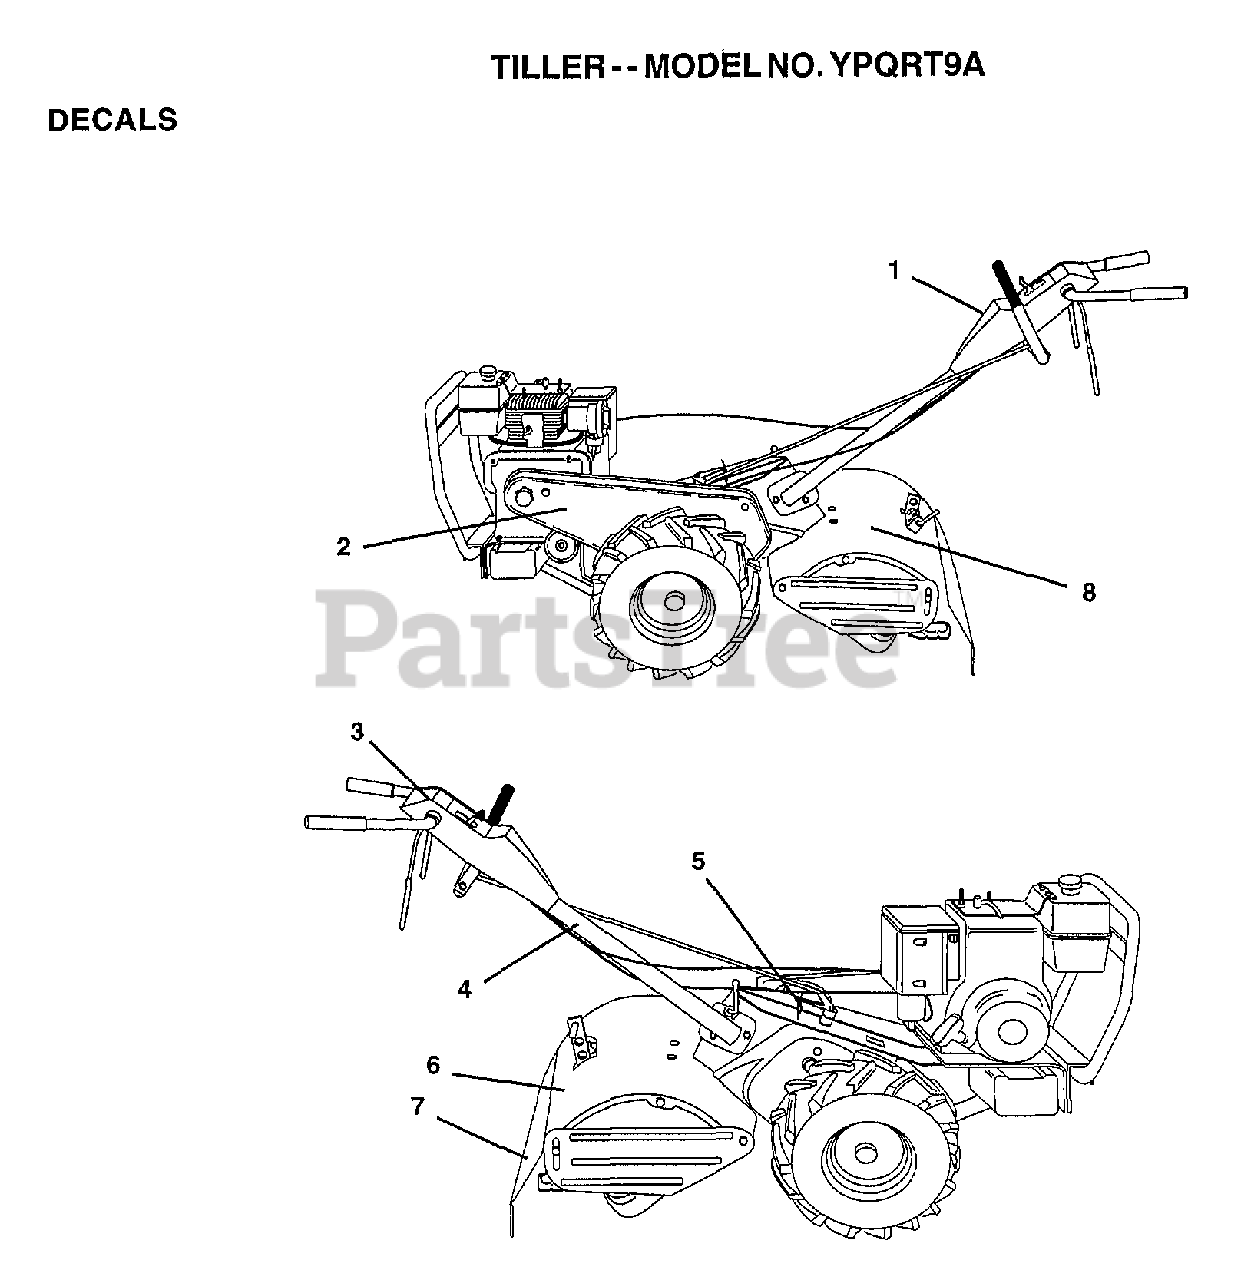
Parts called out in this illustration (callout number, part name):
1	DECAL PANEL CNTRL
2	DECAL GUARD BELT
3	DECAL INST PNL 21
4	DECAL TI
5	DECAL.SHIFT.IND.
6	DECAL.CAUTION
8	DECAL SHIELD TINE
